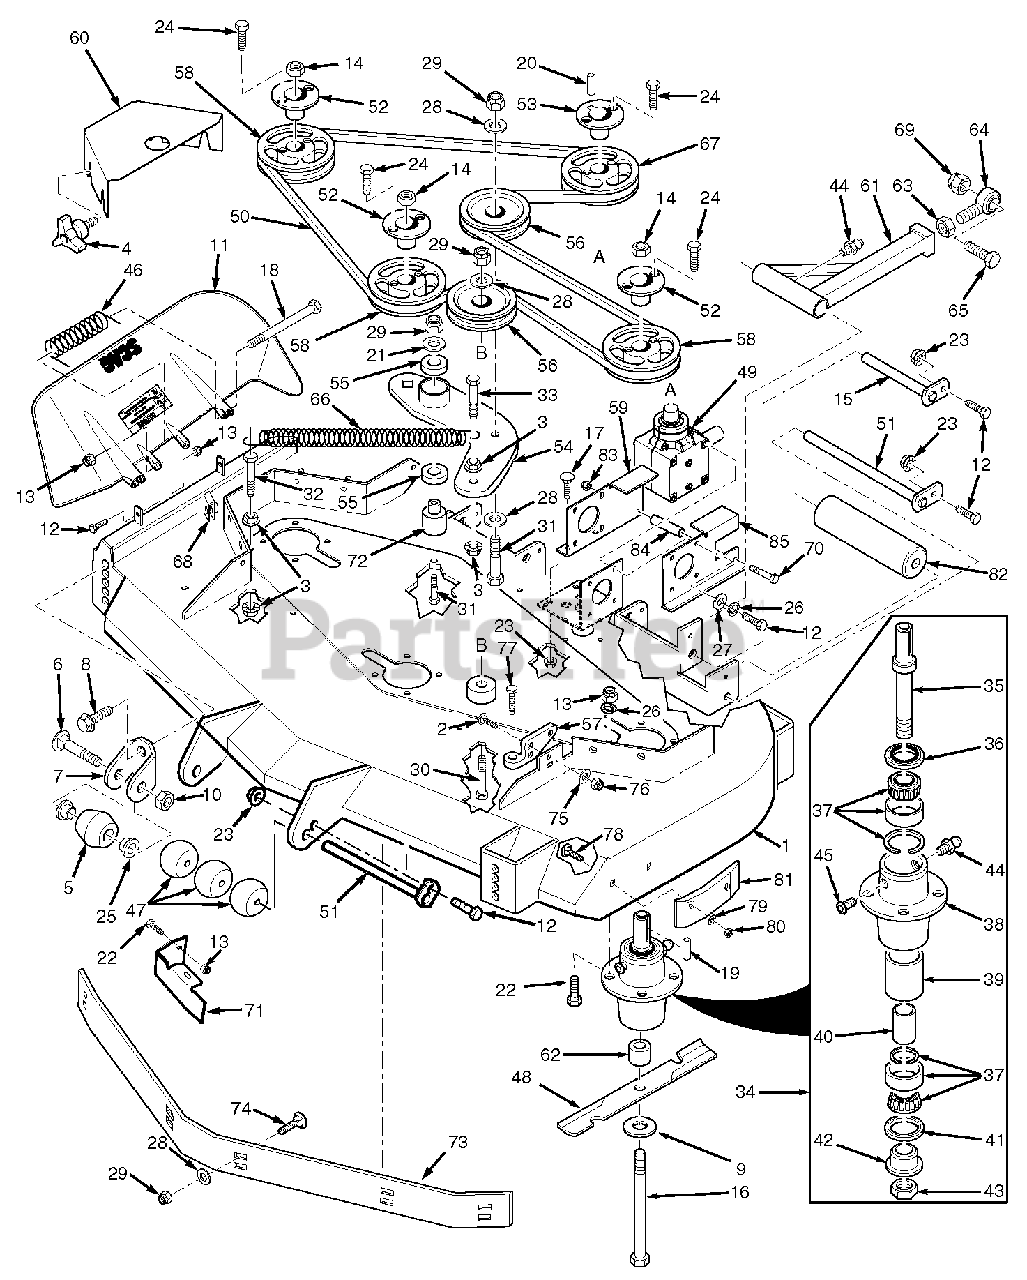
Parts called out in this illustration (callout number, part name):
1	Cutter Deck Velocity Plus
2	Bolt, Carriage 7/16-14 x 1-1/4"
3	Nut, Hex Serr. Flng. 3/8-16
4	Wing Nut, 3/8-16
5	Anti-Scalp Wheel
6	Bolt, Carriage 3/8-16 x 4"
7	Anti-Scalp Wheel Bracket
8	Bolt, Hex Serr. Flng. 3/8-16 x 1"
9	Flatwasher, 5/8" Hardened
10	Locknut, 3/8-16 Center Lock
11	Discharge Chute
12	Bolt, Hex Hd. 5/16-18 x 1-1/2" - Rear
13	Nut, Hex Elastic Stop 5/16-18 Grd. 8
14	Nut, 5/8-11 UNC
15	Pusharm Shaft
16	Bolt, Hex Hd. 5/8-11 x 9-1/2"
17	Bolt, Carriage 5/16-18 x 3/4"
18	Bolt, Hex Hd. 5/16-18 x 4-1/2"
19	Key, 1/4 x 1/4 x 2"
20	Key, 1/4 x 1/4 x 1-1/4"
21	Flatwasher, 3/8 (.39 x .938 x .105") HD
22	Bolt, Hex Hd. 5/16-18 x 1-3/4"
23	Nut, Hex Serr. Flng. 5/16-18
24	Bolt, Hex Hd. 1/4-20 x 1" Grd. 8
25	Bushing, .376" I.D. Oilite
26	Lockwasher, 5/16"
27	Flatwasher, 5/16" (.375 x .875 x .083")
28	Flatwasher, 3/8" (.391 x .938 x .105")
29	Nut, Hex Elastic Stop 3/8-16
30	Bolt, Hex Hd. 3/8-16 x 3-1/4"
31	Bolt, Hex Hd. 3/8-16 x 3"
32	Bolt, Hex Hd. 3/8-16 x 1-1/2"
33	Bolt, Hex Hd. 3/8-16 x 1-1/2" Grd. 8
34	Spindle Assembly
35	Spindle Shaft
36	Seal, Top
37	Bearing Assembly
38	Spindle Housing
39	Spacer, Outside
40	Spacer, Inside
41	Seal, Bottom
42	Spindle Bushing, Bottom
43	Nut, Special 1-1/16-18
44	Grease Fitting
45	Relief Fitting, Tapered Spindle
46	Spring, Discharge Chute
47	Wheel, Anti-Scalp
48	Cutter Blade, 21"
49	Gearbox Assembly, Deck Drive
50	Belt, Cutter Deck Drive
51	Roller Shaft
52	Tapered Hub, 1-1/8" Bore
53	Tapered Hub, 1" Bore
54	Idler Arm, Cutter Deck
55	Bearings, Ball
56	Pulley, Idler
57	Lever Assembly, Deck Level
58	Pulley, 6.35" O.D. (61")
59	Mounting Plate, RH Gearbox
60	Belt, Cover
61	Pusharm
62	Spacer, Spindle Bottom
63	Nut, Hex Hd. 5/8-18 UNF
64	Rod End, 5/8" Male RH Thread
65	Bolt, Hex Hd. 5/8-11 x 4-1/2"
66	Spring, Cutter Deck
67	Pulley, 6.75 O.D.
68	U-Nut, 3/8-16
69	Nut, Hex Elastic Stop 5/8-11
70	Bolt, Hex Hd. 5/16-18 x 4-3/4"
71	Discharge Baffle 61V
72	Pivot, Idler - Short
73	Baffle, Custom Cut 61V
74	Bolt, Carriage 3/8-16 x 1"
75	Flatwasher, 7/16" (.500 x 1.25 x .083")
76	Nut, Elastic Stop 7/16-14
77	Bolt, Deck Adjust
78	Bolt, Carriage 5/16-18 x 3/4"
79	Flatwasher, 5/16"
80	Nut, Center Lock 5/16-18
81	Wear Pad
82	Wheel, Anti-Scalp
83	Nut, Elastic Stop 5/16-18
84	Spacer, Gearbox Mount
85	Mounting Plate, LH Gearbox
